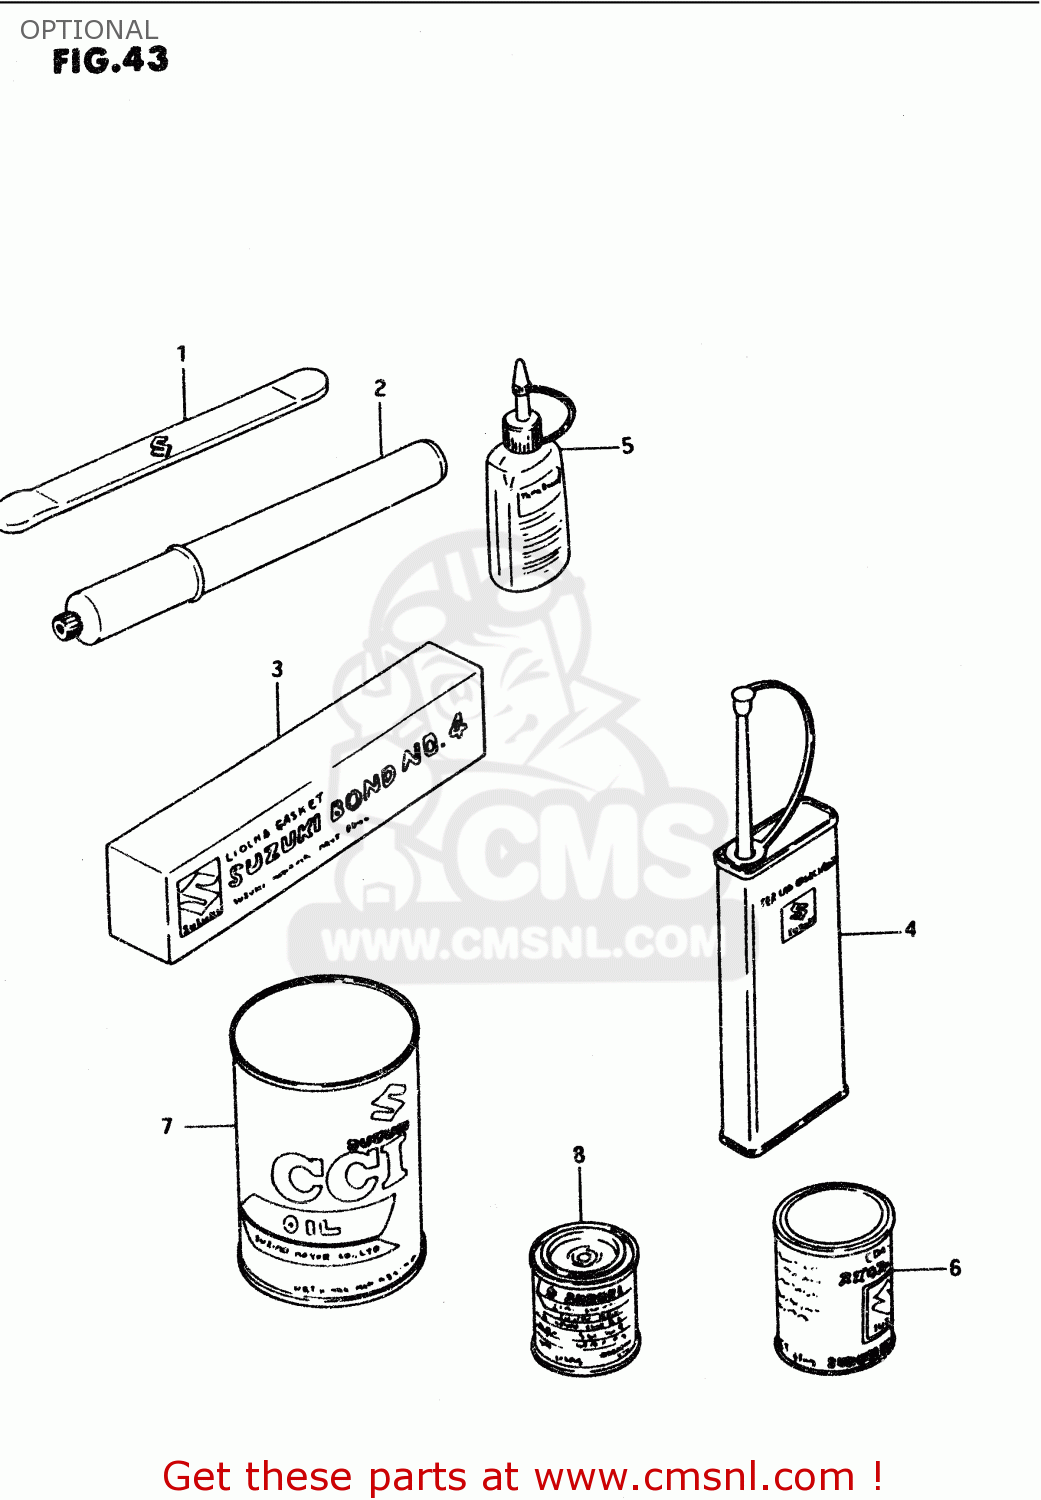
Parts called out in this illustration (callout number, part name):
1	LEVER,TIRE
2	INFLATOR, AIR
3	BOND 1104
4	THREAD LOCK NO.1401 CLEAR 200G
5	THREAD LOCK NO
6	GREASE(C)EP2 LITHIUM 150G
7	CCI OIL
8	PAINT,BLACK
